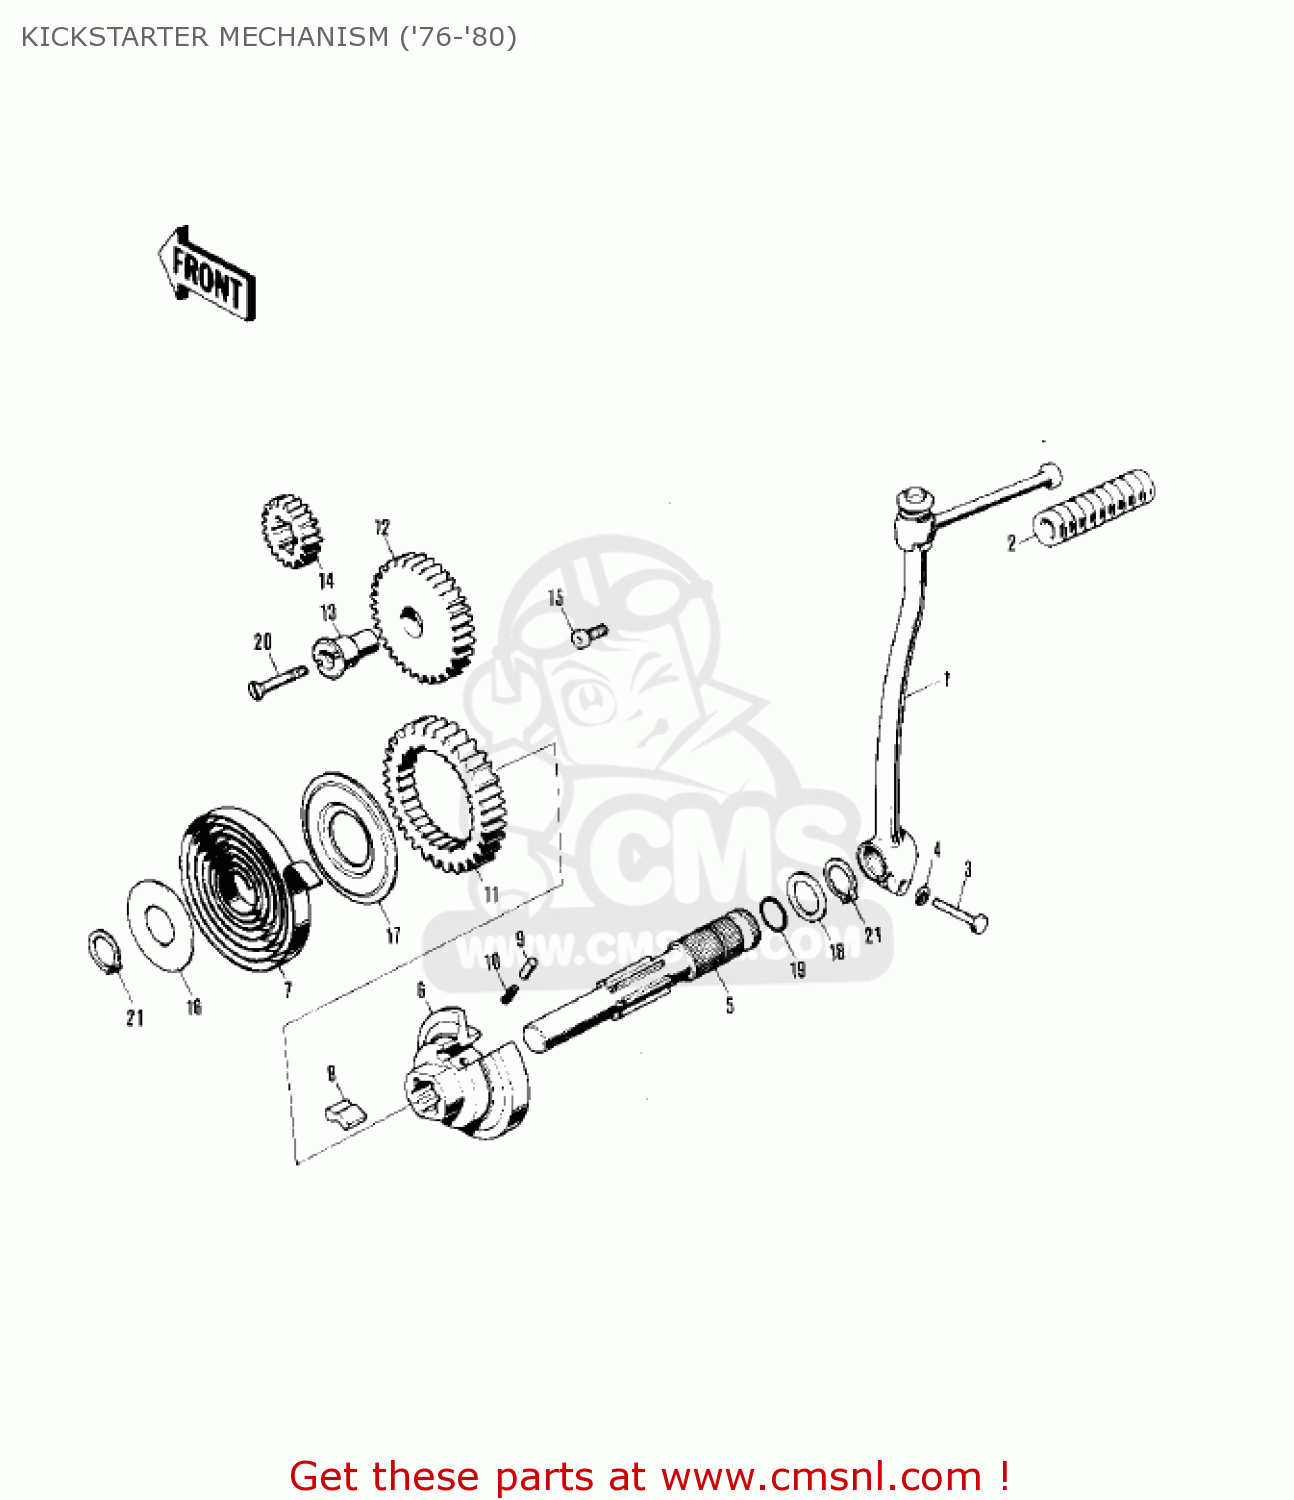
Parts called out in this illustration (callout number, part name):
1	PEDAL-KICKSTARTER
2	RUBBER-KICK PEDAL
3	BOLT-UPSET,6X25
4	WASHER-SPRING,6MM
5	SHAFT-KICKSTARTER
6	DRUM,KICKSTARTER
7	SPRING-KICKSTARTER
8	PAWL-KICKSTARTER
9	PIN-KICKSTARTER PAWL
10	SPRING-KICK PAWL
11	GEAR-KICKSTARTER
12	IDLE GEAR
13	SHAFT-IDLE GEAR
14	PINION-KICKSTARTER
15	STOPPER,KICKSTARTER
16	PLATE-KICK SPRG HLDER
17	PLATE,KICK GEAR
18	WASHER,16.5X26X1.4
19	RING-O,16MM
20	SCREW,CNTRSNK HD,5X30
21	CIRCLIP-TYPE-C,16MM
